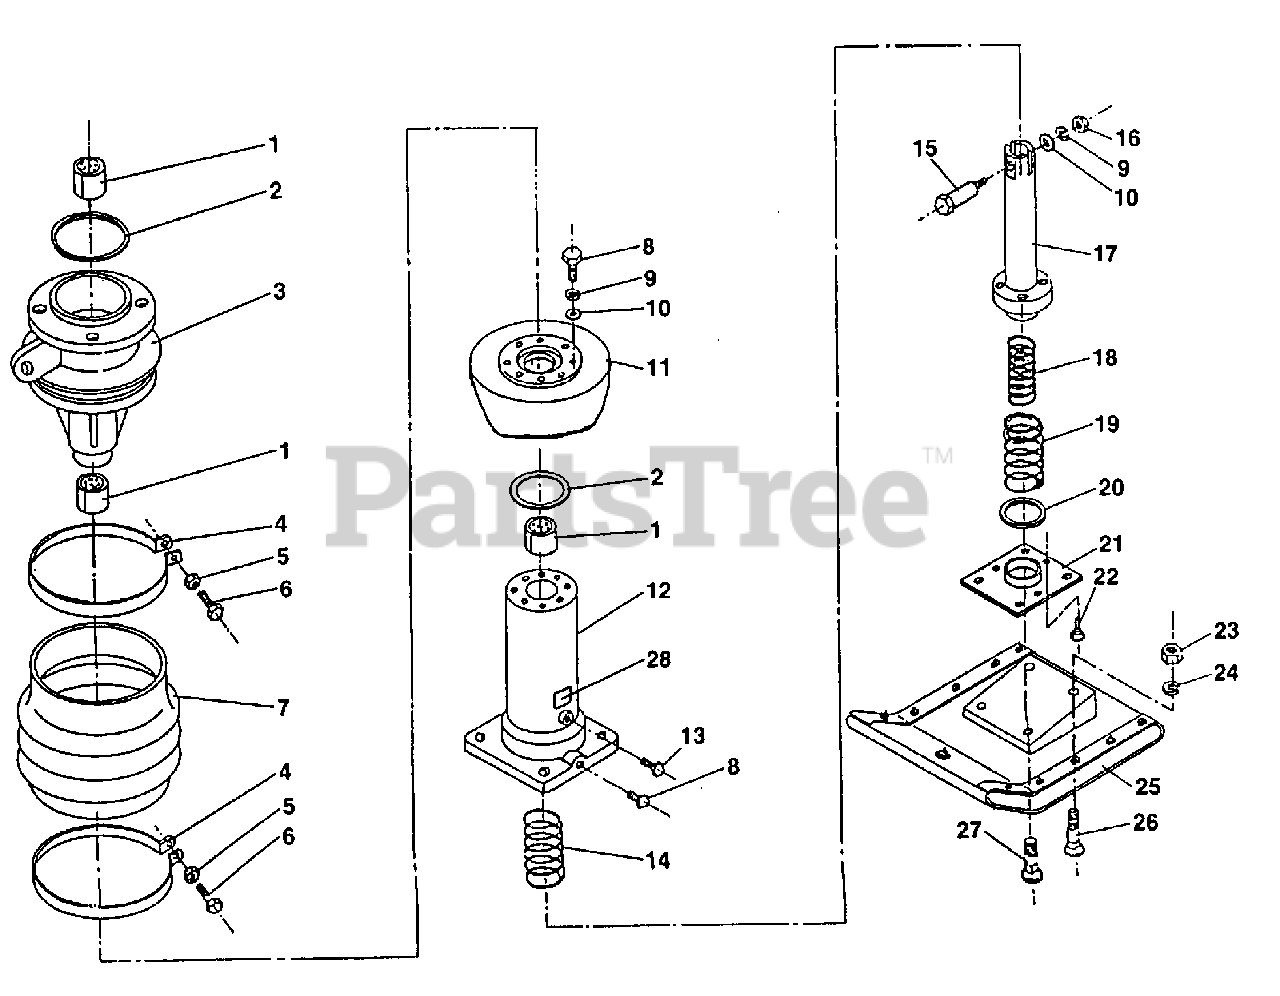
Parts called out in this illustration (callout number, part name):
2	O-RING (G-105)
3	CYLINDER
4	BELLOWS BAND
5	NUT- Hex m1O
6	BOLT- Hex m1O x 60
7	BELLOWS- Complete
8	BOLT- Hex m8 x 20
9	WASHER- Spring m8
10	WASHER- Plate m8
11	BELLOWS BASE
12	FOOT CYLINDER
13	BOLT- Hex m8 x 10
14	CYLINDER SPRING- Upper
15	PIN- Rod
16	NUT- Nylon m8
17	ROD- Piston
18	CYLINDER SPRING- Lower
19	CYLINDER SPRING- Lower
20	O-RING (G-90)
21	COVER- Cylinder
22	BOLT- Hex
23	NUT- Nylon m12
24	WASHER- Spring m12
25	SHOE- Ramming
26	BOLT- Flat hd. m12 x 105
27	BOLT- m12 x 95
28	CHECK OIL DECAL
